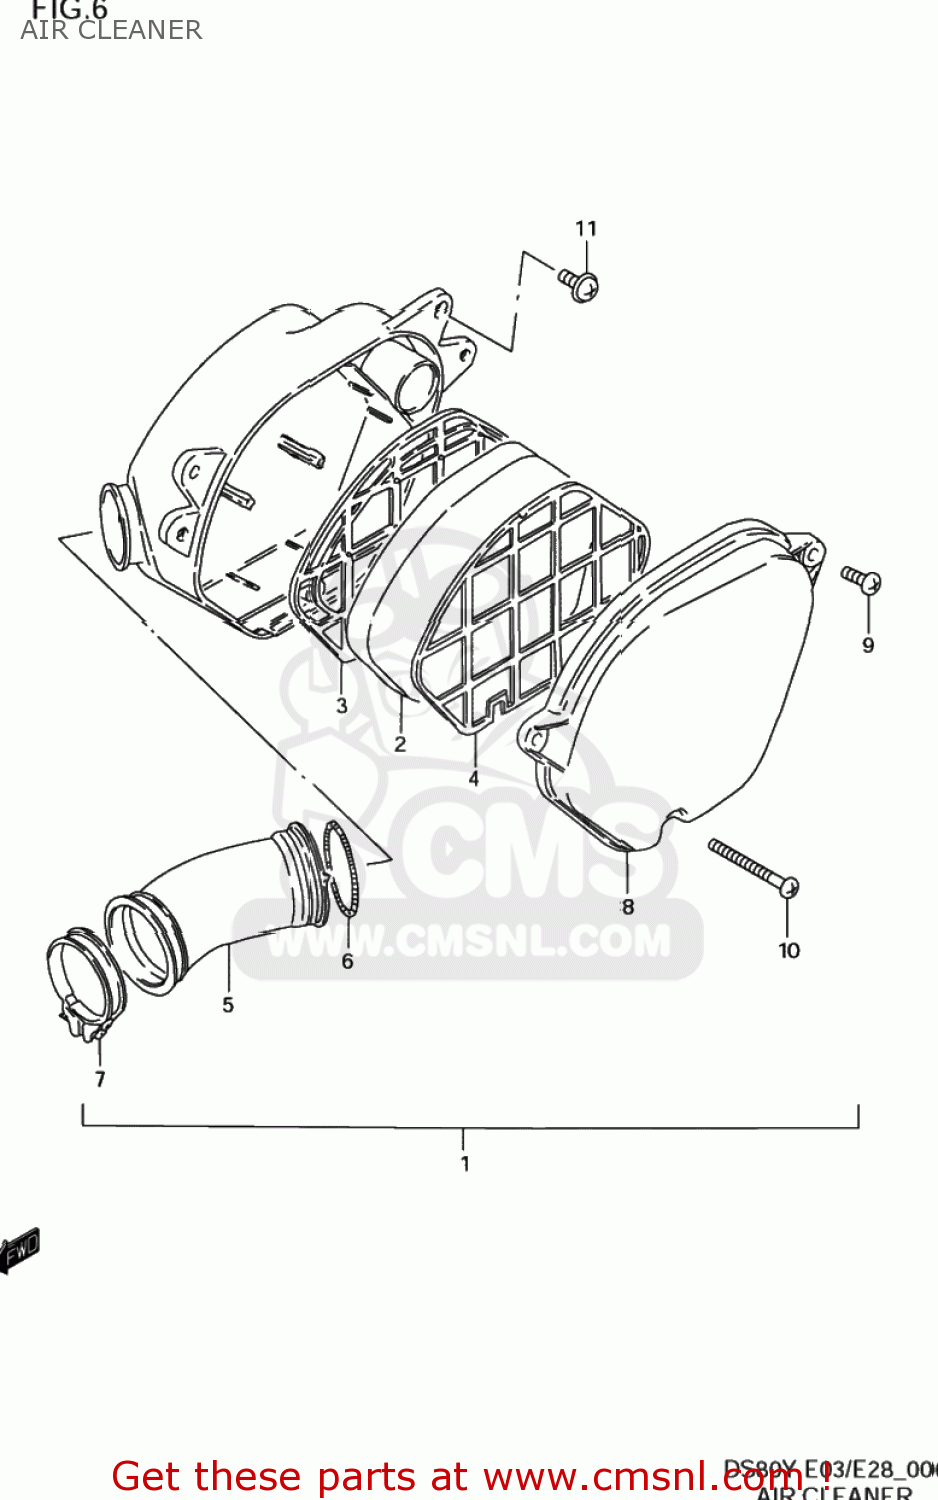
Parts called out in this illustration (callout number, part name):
1	CLEANER ASSY,AIR
2	FILTER
3	HOLDER,FILTER INNER
4	HOLDER,FILTER OUTER
5	TUBE,OUTLET
6	SPRING,AIR CLEANER SIDE
7	CLAMP
8	CAP,CLEANER
9	SCREW
10	SCREW
11	SCREW(6X16)
